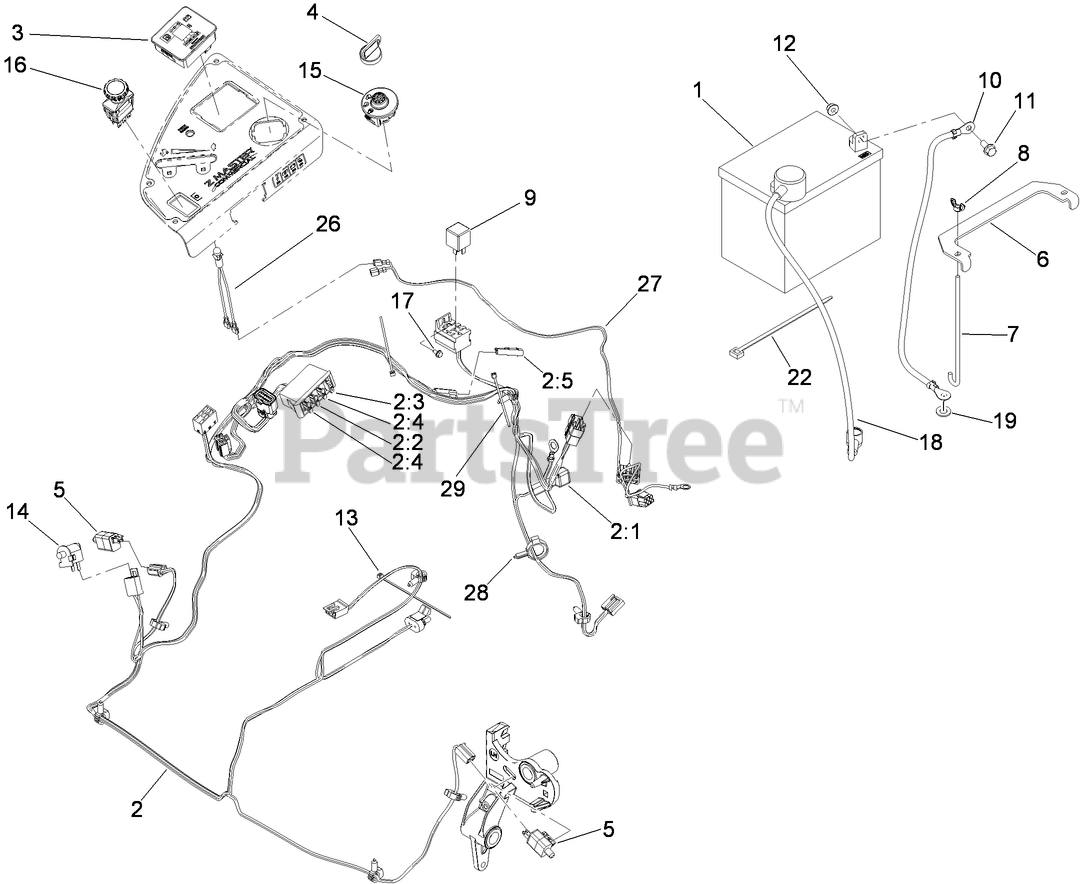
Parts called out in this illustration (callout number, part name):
1	BATTERY-WET
2	HARNESS-WIRE, MAIN
2:2	FUSE-BLADE, 10 AMP
2:3	FUSE-BLADE, 15 AMP
2:4	FUSE-BLADE, 25 AMP
2:5	CAP-PLUG
3	FUEL/HOUR METER ASM
4	KEY-IGNITION
5	SWITCH
6	STRAP-TIE DOWN, BATTERY
7	BOLT-HOLDDOWN
8	WINGNUT
10	CABLE-BATTERY, NEGATIVE
11	SCREW-HHF
12	NUT-HF, NI
13	TIE-CABLE
14	SWITCH-BAIL
15	SWITCH-IGNITION
16	SWITCH-PTO, 10 AMP
17	SCREW-HWH
18	CABLE-BATTERY, POSITIVE
19	WASHER-FLAT
22	TIE-PLASTIC
26	INDICATOR-LED, RED
27	HARNESS-LIGHT, INDICATOR
28	CLAMP-HOSE
29	TIE-CABLE
